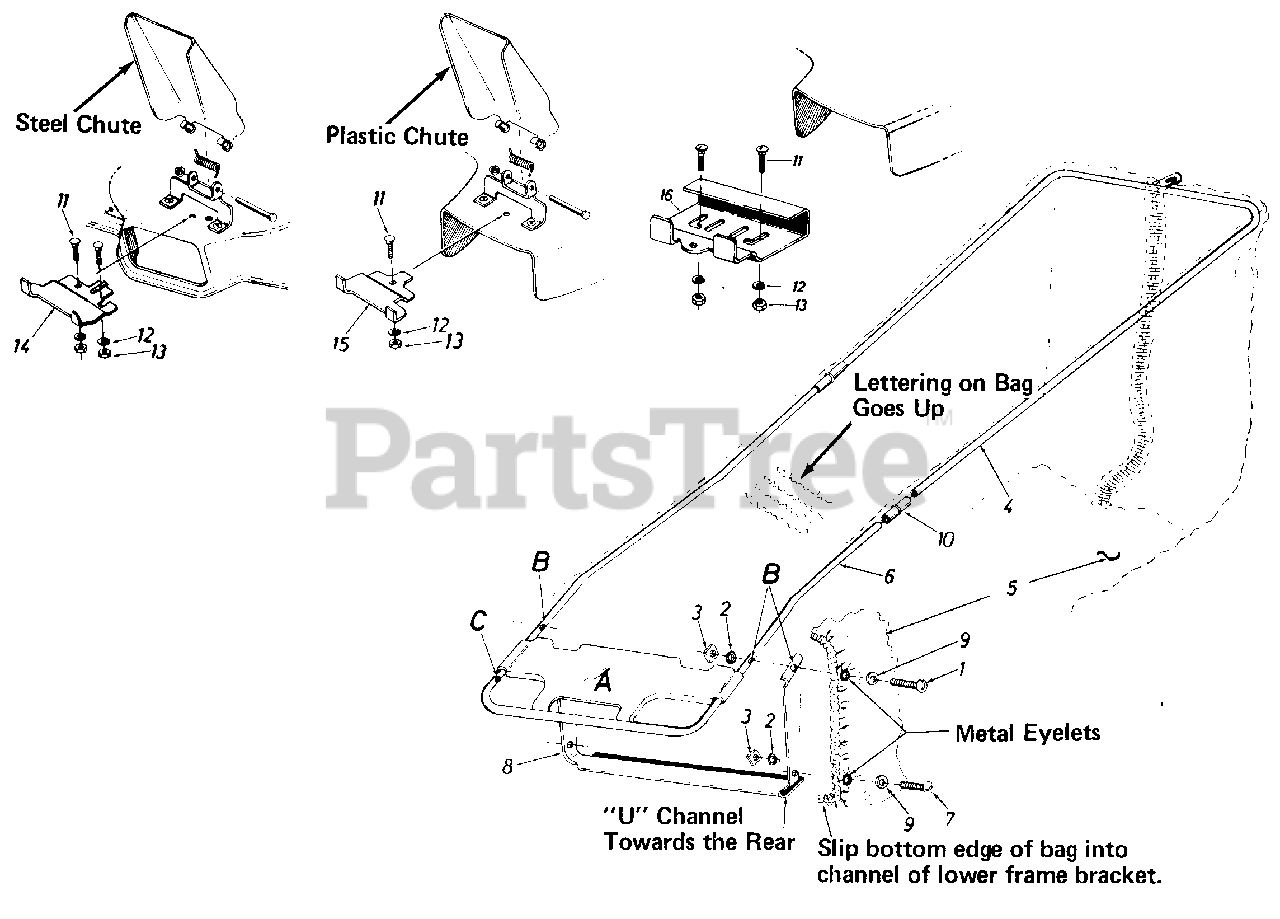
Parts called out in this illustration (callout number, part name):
1	Truss Mach. Scr. #10-24 x 1.00" Lg.*
2	Ext. L-Wash. #10 Scr.*
3	Sq. Nut #10-24 Thd.*
4	Frame Upper Half
5	Grass Catcher Bag
6	Frame Lower Half
7	Truss Mach. Scr. #10-24 x .62" Lg.*
8	Lower Frame Bracket
9	Fl.-Wash. .203 I.D. x .41 O.D.
10	Tubing Connector
11	Carriage Bolt
12	Lock Washer 1/4" I.D.*
13	Hex Nut 1/4-20 Thd.
14	Adapter Plate
15	Adapter Plate
16	Adapter Plate
